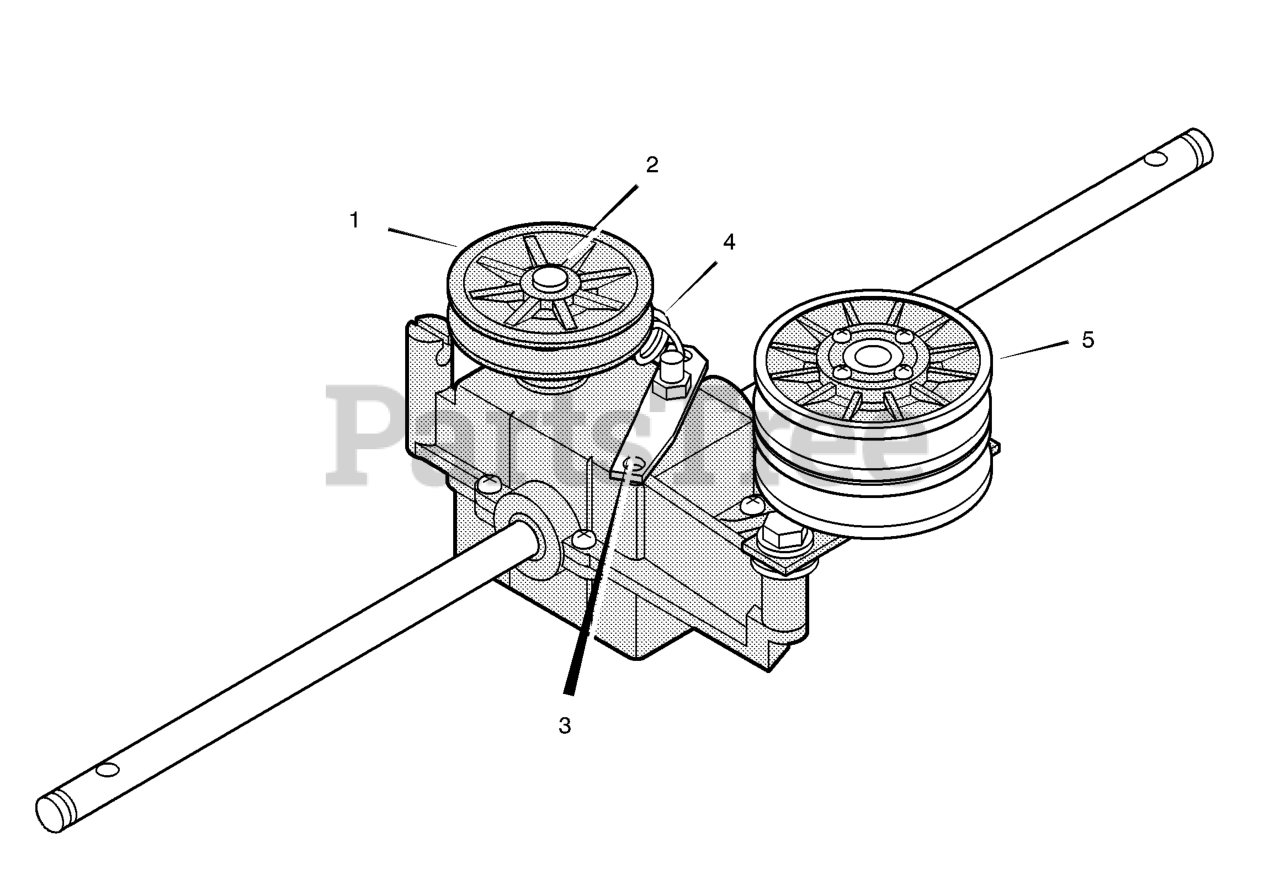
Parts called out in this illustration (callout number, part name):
1	Pulley
2	Attachment Pin, Pulley
3	Clutch Lever Assembly
4	Spring, Clutch Return
5	Variator Assembly
